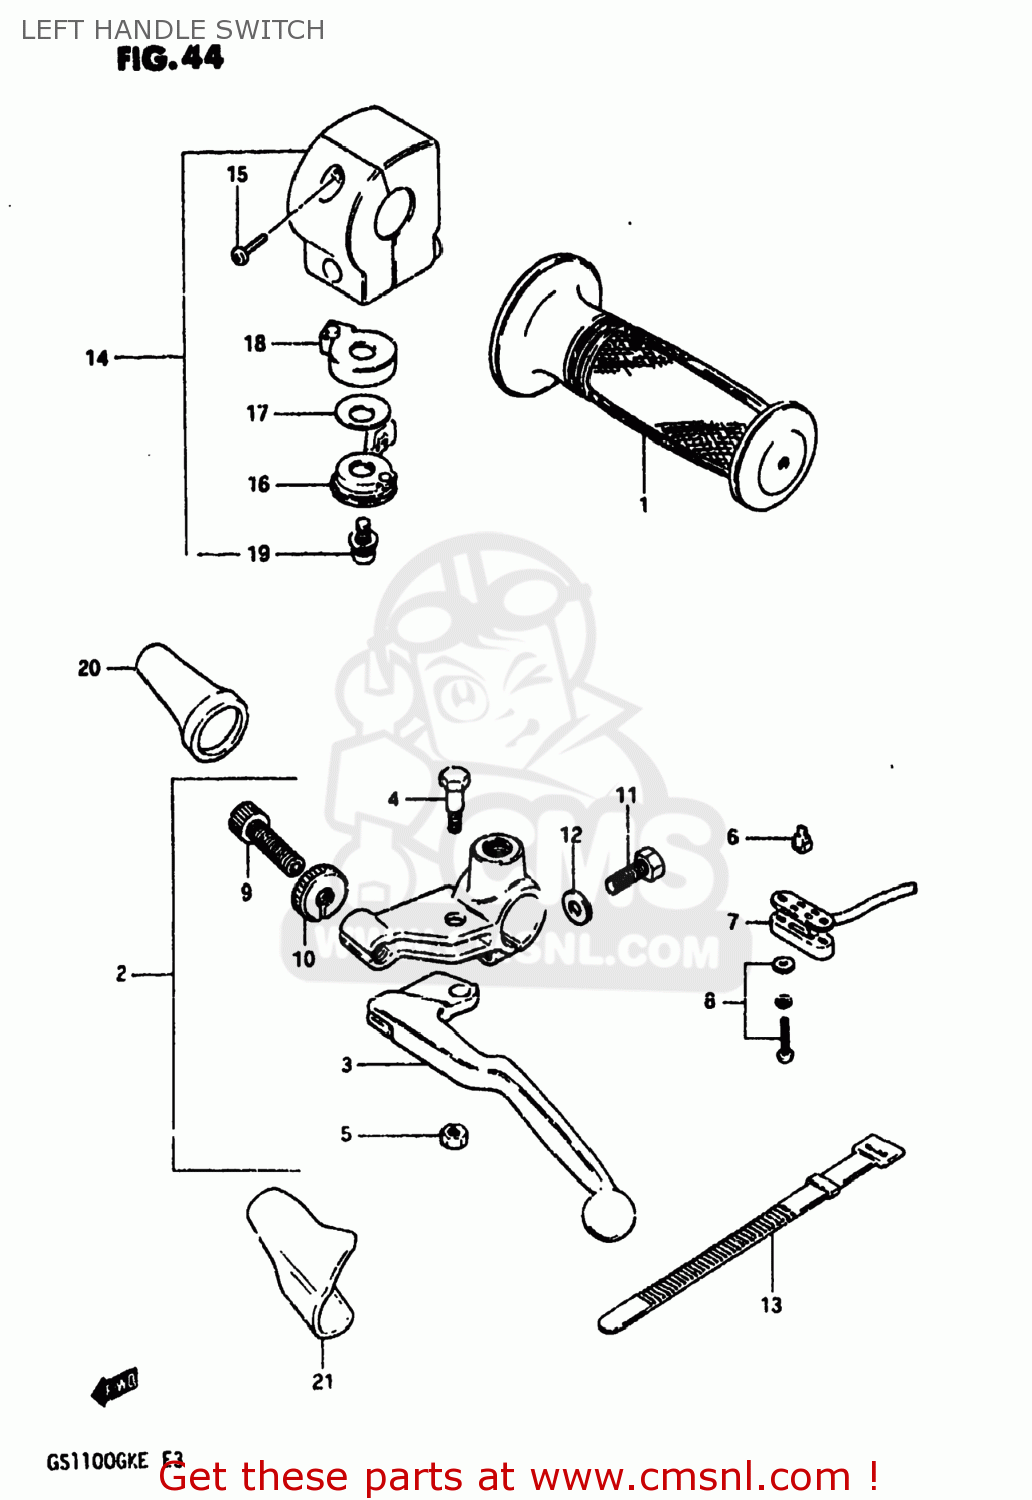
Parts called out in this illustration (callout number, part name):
1	GRIP
2	LEVER ASSEMBLY
3	LEVER,CLUTCH
4	BOLT,LEVER PIVOT
5	NUT 6MM
6	CONTACT,SWITCH
7	COVER,FR BK TERMINAL BASE
8	SCREW
9	ADJUSTER,CABLE
10	NUT,CABLE ADJUSTER
11	BOLT,CLUTCH LEVER HOLDER
12	WASHER
13	CLAMP(L:120)
14	SWITCH ASSY,HANDLE,L
15	SCREW
16	LEVER,STARTER
17	WASHER,ADJUSTER
18	BODY,STARTER LEVER
19	SCREW,CHOKE LE
20	BOOT,CLUTCH CABLE
21	COVER,CLUTCH LEVER
